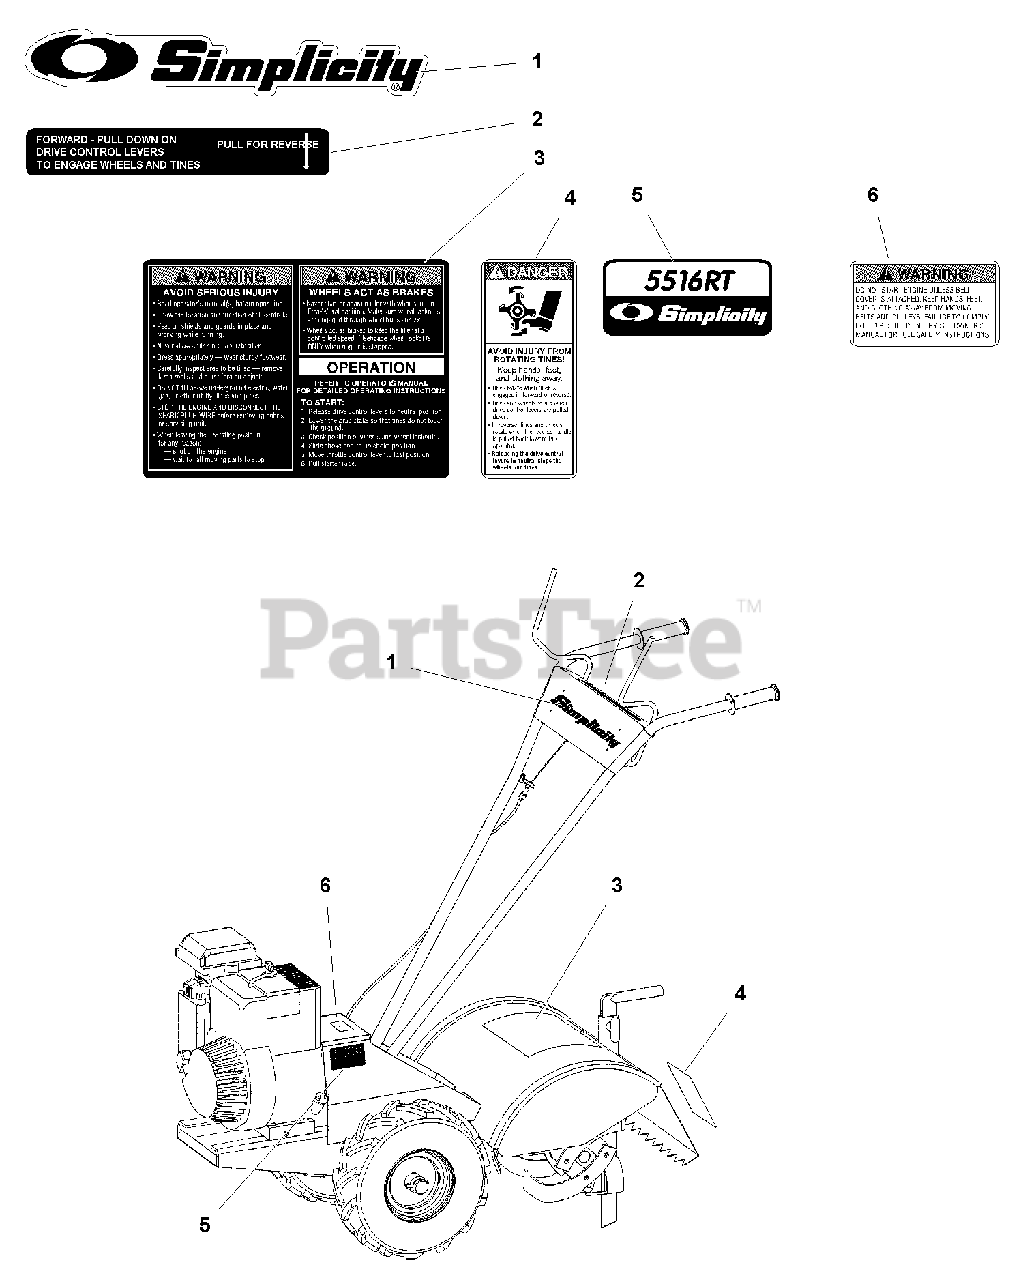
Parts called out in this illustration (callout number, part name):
1	DECAL, Simplicity, w/Logo
2	DECAL, Console Forward/Reverse Instructions
3	DECAL, Hood, Operator Instructions
4	DECAL, Danger, Tine Hood
5	DECAL, Belt Cover
6	DECAL, Warning, Belt Cover
